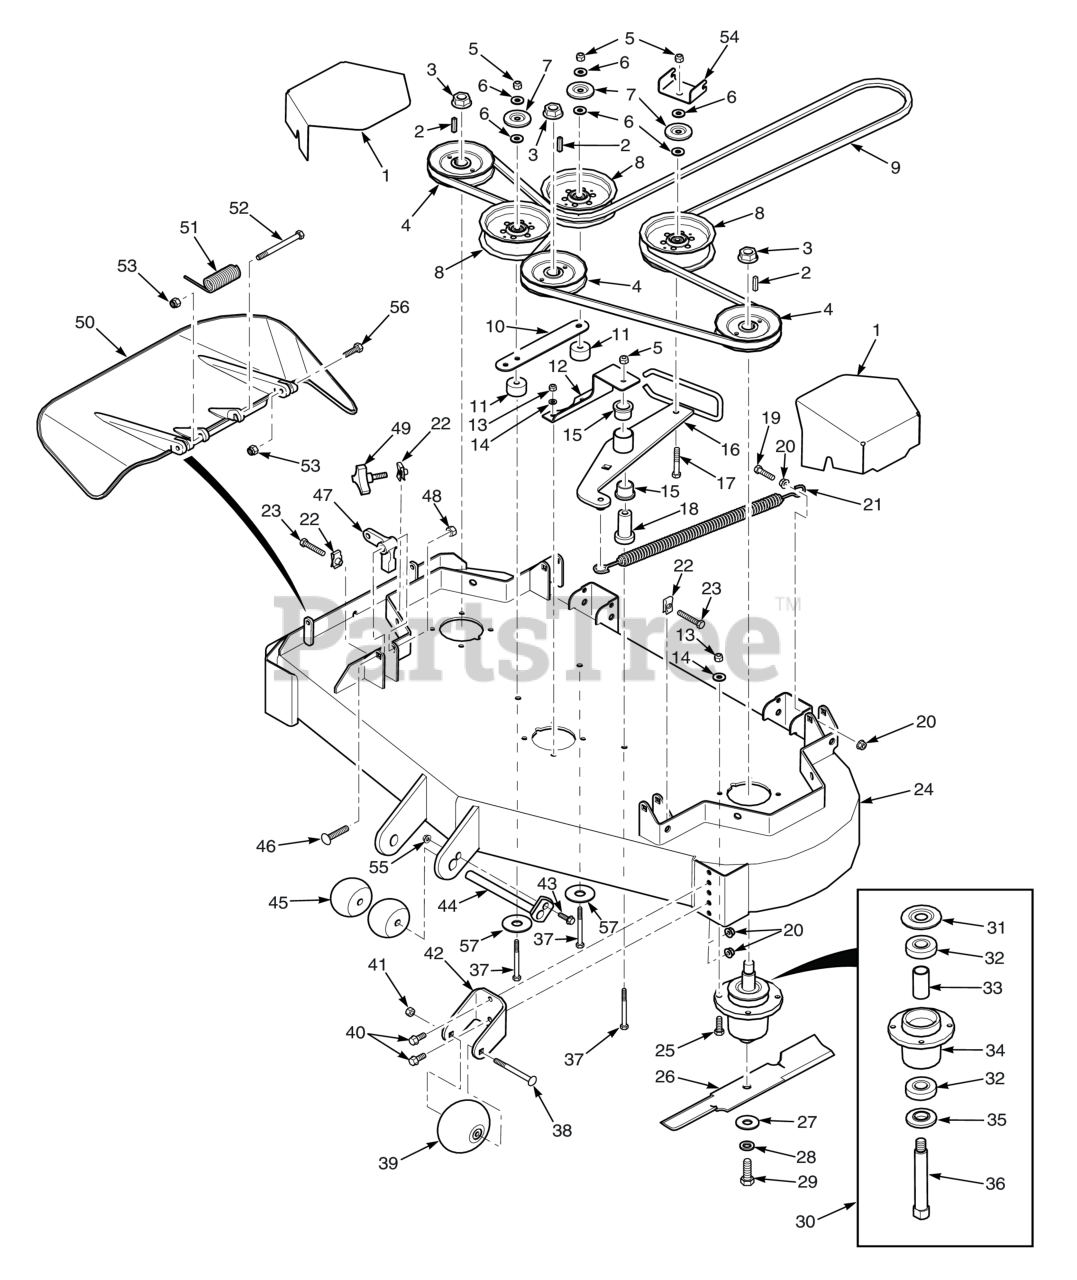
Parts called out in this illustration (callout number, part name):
1	Belt Cover
2	Key, 1/4 x 1/4 x 1.25" Pulley Mtg.
3	Nut, 3/4-16 Spriral Lock
4	Pulley, 6.32" OD - 25mm Bore
5	HEX NUT, ELASTIC STOP LOCK, 3/8-16
6	Flatwasher, 3/8 (.391 x .938 x .105 HD) Grade 8
7	Quick Pin, 5/16" Dia.
8	Pulley, 5" Idler
9	Belt, Cutter Deck
10	Brace, Pulley
11	Spacer, Idler Pulley
12	Support, Idler Pivot
13	Lock Nut, 5/16-18 Elastic Stop Grade 8
14	Lockwasher, 5/16 (.317 x .586 x .078) Helical Spring
15	Bearing, Plastic
16	Idler Arm (incl. item #15)
17	Capscrew, Hex Head 3/8-16 x 2-1/2"
18	Pivot, Idler
19	Bolt, Hex Head 3/8-16 x 1-1/2" Grade 8 Black
20	NUT, 3/8-16 SERRATED FLANGE HEX HEAD
21	Spring, Cutter Deck Idler
22	U-Nut, 3/8-16 (short)
23	Bolt, Hex Head 3/8-16 x 2" Special Lock
24	Cutter Deck w/Decals, SPZ61
25	Bolt, Hex Head 5/16-18 x 1-1/2" (Right Front Engine Mounting, Briggs and Kohler Only)
26	Cutter Blade, 21" Standard
27	Flatwasher, 5/8-.688 x 1-3/4 x .134 HD
28	Lockwasher, 5/8" Spring
29	Bolt, Hex Head 5/8-11 x 1-1/2"
30	Spindle Assembly
31	Debris Shield
32	Bearing
33	Spacer, Bearing
34	Spindle Housing Assembly
35	Protector, Bearing
36	Shaft, Spindle
37	Bolt, Hex Head, 3/8-16 x 3-1/2"
38	Bolt, Hex Head 3/8-16 x 3-1/2"
39	Bolt, Carriage 3/8-16 x 4"
40	Capscrew, 3/8-16 x 1.0" Serrated Flange Hex Hd
41	Bolt, Hex Head 3/8-16 x 1" Ser. Flg.
42	Bracket, Anti-Scalp, (Black)
43	Bolt, Heax Head 5/16-18 x 1" (48V / 52V)
44	Shaft Weldment, Guide Roller
45	Wheel, Anti-Scalp
46	Bolt, Carriage 7/16-14 x 2-1/4"
47	Bolt, Carriage 7/16-14 x 2-1/4"
48	HEX LOCKNUT, ELASTIC STOP, 7/16-14
49	Knob, w/stud 3/8-16 x 1-1/4"
50	Discharge Chute Assembly
51	Spring, Discharge Chute
52	Bolt, 5/16-18 x 4-3/4" Hex Head
53	HEX NUT, ELASTIC STOP LOCK, 5/16-18
54	Bracket, Belt Guide
55	Nut, Serrated Flange 5/16-18 (Right Front Engine Mounting, Briggs and Kohler Only)
56	Bolt, Hex Head 5/16-18 x 1-1/2" - Front
57	Flatwasher, 3/8-.406 x 2.25" x .1875
